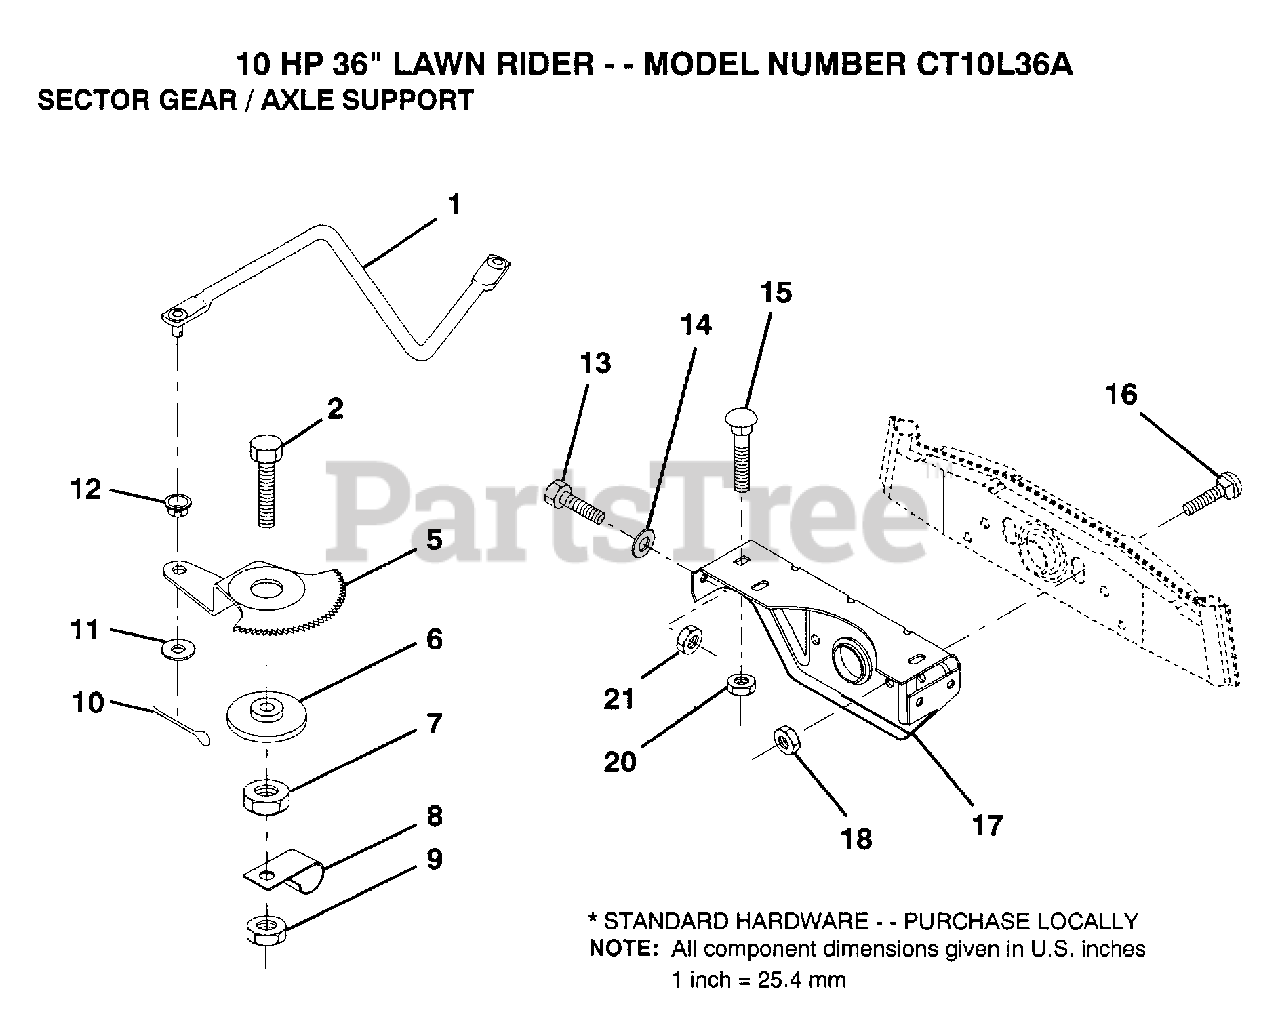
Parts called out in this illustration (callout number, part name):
1	DRAG LINK
2	"BOLT,HEX"
5	GEAR SECTOR
6	BUSHING
7	NUT
8	CLIP INSULATOR
9	NUT LTV
10	COTTER PIN
11	WASHER
12	BUSHING.DRAGLINK
13	BOLT
14	WASHER
15	BOLT
16	BOLT
17	"SUPT,FRT AXLE"
